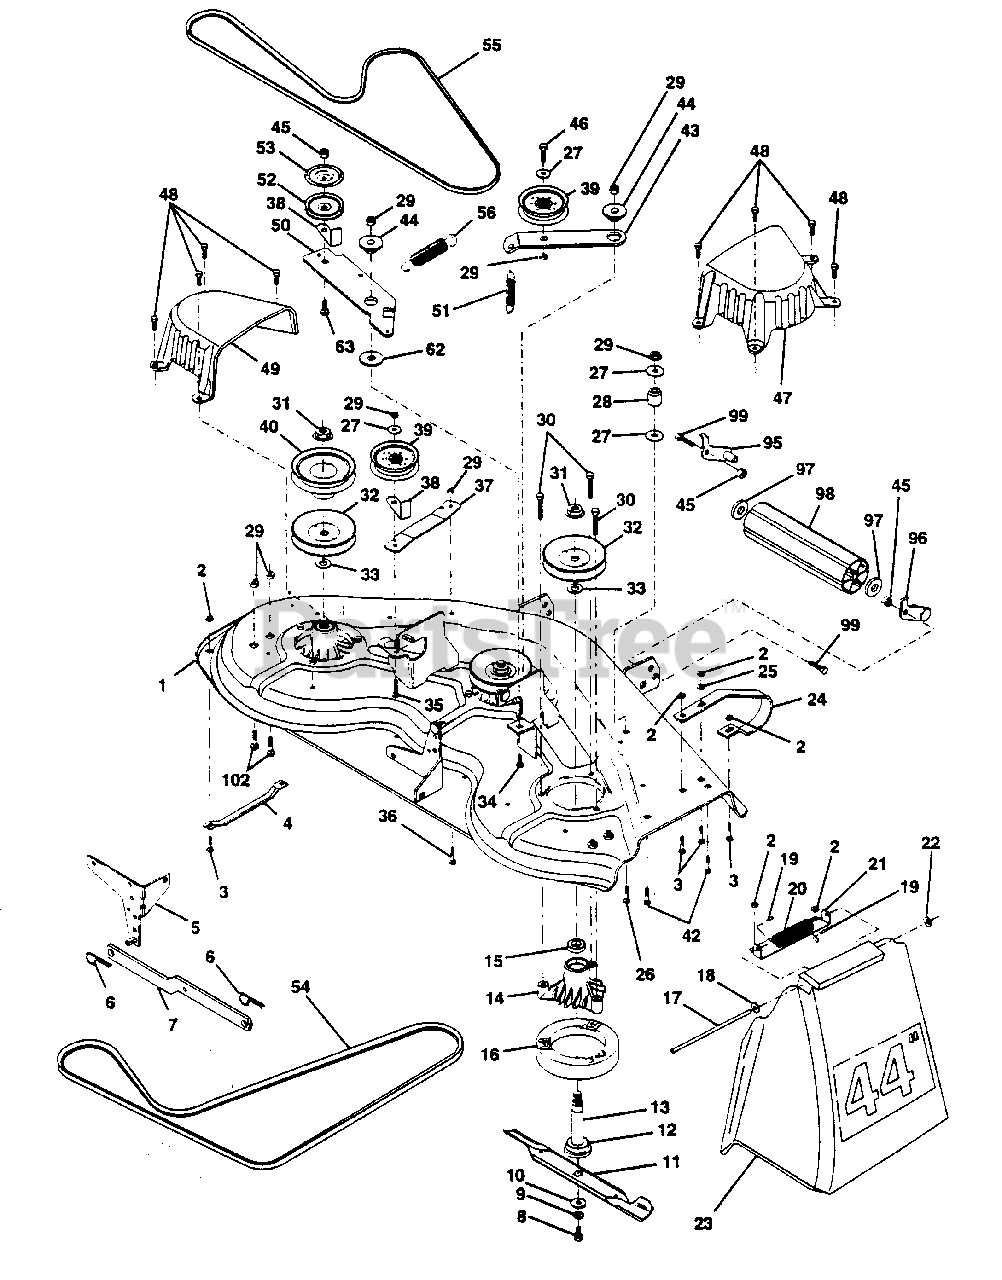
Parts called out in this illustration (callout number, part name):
1	Deck Asm., Mower 44" Vented (AYP part number)
2	Locknut, Hex W/Ins 5/16-18 Unc (AYP part number)
3	Bolt, Carriage 5/16-18 x 3/4 (AYP part number)
4	Runner, Mower LH (AYP part number)
5	Bracket Asm., Sway Bar (AYP part number)
6	Retainer, Spring (AYP part number)
7	Arm Suspension, Rear (AYP part number)
8	Bolt 3/8-24 x 1.25 Gr. 8 Patched (AYP part number)
9	Washer, Lock Hvy 3/8 Unplated (AYP part number)
10	Washer, Hard Blade Mower Vented (AYP part number)
11	Blade (3 Required) (AYP part number)
12	Bearing, Ball #6204 (Mandrel) (AYP part number)
13	Shaft Asm., W/Lower Brg (Includes Key No. 12) (AYP part number)
14	Housing, Mandrel 44" Vent (AYP part number)
15	Bearing, Ball Mandrel (AYP part number)
16	Stripper, Mower Vented (AYP part number)
17	Rod, Hinge (AYP part number)
18	Washer 11/32 x 5/8 x 16 Ga. (AYP part number)
19	Cap, Sleeve (AYP part number)
20	Spring, Torsion Deflector (AYP part number)
21	Bracket, Deflector (AYP part number)
22	Nut, Push (AYP part number)
23	Shield, Deflector Mower (AYP part number)
24	Runner, RH (AYP part number)
25	Washer 11/32 x 3/4 x 16 Ga. (AYP part number)
26	Bolt, Carriage 3/8-16 x 1-3/4 Gr. 5 (AYP part number)
27	Washer 13/32 x 13/16 x 16 Ga. (AYP part number)
28	Spacer, Spring Stop Idler
29	Nut, Lock Hex W/Wsh 3/8-16 Unc (AYP part number)
30	Screw Thdrol. Hex Hd Zinc Mower (AYP part number)
31	Nut, Flg Top Lock Cntr 9/16
32	Pulley, Mandrel (AYP part number)
33	Washer, Spacer Mower Vented (AYP part number)
34	Bolt, Carriage 3/8-16 x 1-1/4 (AYP part number)
35	Bolt, Carriage 3/8-16 x 2 (AYP part number)
36	Bolt, Carriage 3/8-16 x 1 Gr. 5 (AYP part number)
37	Stiffener, Arm Idler (AYP part number)
38	Keeper, Belt Idler (AYP part number)
39	Pulley, Idler Flat (AYP part number)
40	Pulley, Driven (AYP part number)
42	Bolt, Carriage 5/16-18 Unc x 3/4
43	Arm, Idler Secondary (AYP part number)
44	Spacer, Retainer (AYP part number)
45	Nut, Crownlock 3/8-16 Unc
46	Bolt, Fin Hex 3/8-16 Unc x 1-3/4 (AYP part number)
47	Cover, Mandrel RH (AYP part number)
48	Screw, Thd Roll 1/4-20 x 5/8 (AYP part number)
49	Cover, Mandrel LH (AYP part number)
50	Arm, Idler Primary (AYP part number)
51	Spring, Secondary (AYP part number)
52	Pulley, Idler V Groove (AYP part number)
53	Shield, Idler (AYP part number)
54	V-Belt, Mower Primary
55	V-Belt, Mower Secondary (AYP part number)
56	Spring, Primary (AYP part number)
62	Washer Hardened (AYP part number)
63	Bolt Carriage 3/8-16 x 1-1/2 (AYP part number)
64	Washer 3/8 x 3/4 x 14Ga (AYP part number)
67	Nut Centerlock 3/8-16 (AYP part number)
95	Bracket Asm. Noseroller LH
96	Bracket Asm. Noseroller RH
97	Washer 17/32 x 7/8 x 16 Ga. (AYP part number)
98	Roller, Nose
99	Bolt Hex 3/8-16 x 1 (AYP part number)
102	Bolt Carriage 3/8-16 x 3/4 (AYP part number)
